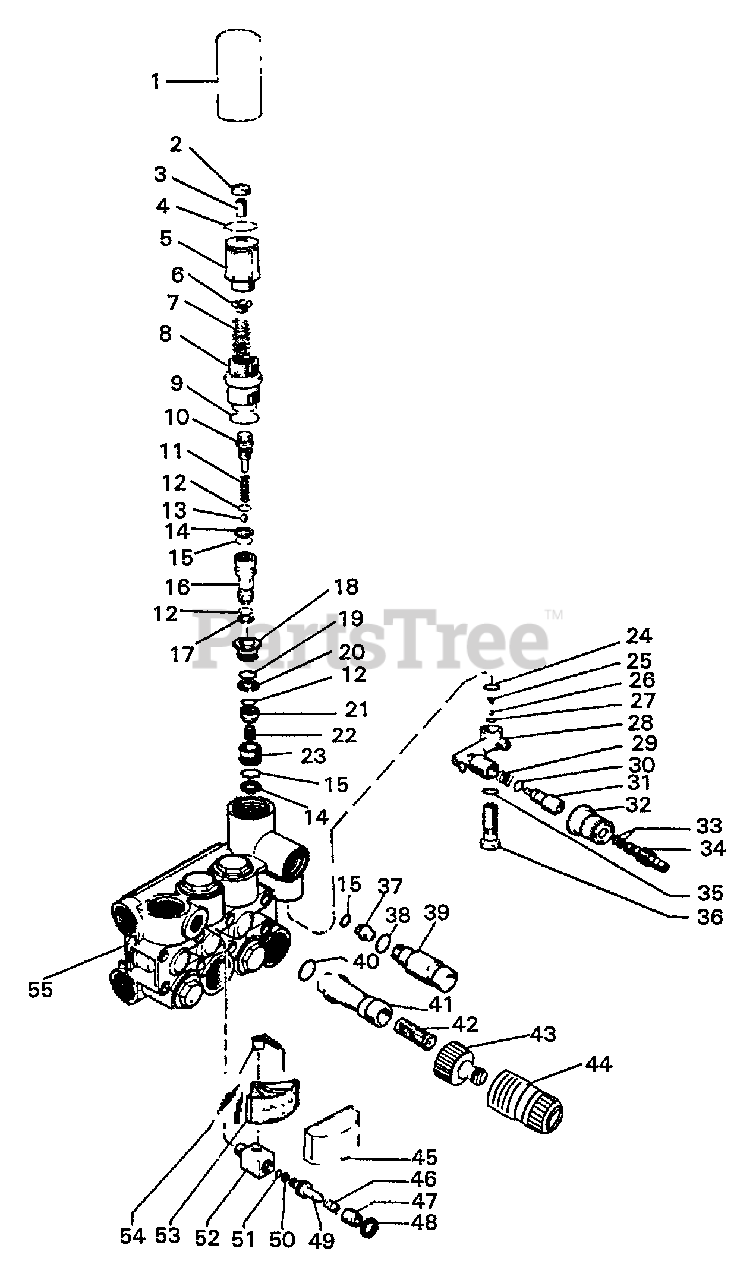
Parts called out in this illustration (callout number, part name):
1	KNOB, PRESSURE REGULATOR
2	NUT - 8
3	SCREW - 8X16
4	O-RING
5	SCREW, PRESSURE SET
6	PLATE, SPRING
7	SPRING
8	BUSHING, GUIDE
9	O-RING - .797 X.103
10	STOPPER, STROKE
11	SPRING
12	O-RING
13	BALL - 9/32"
14	RING, ANTI-EXTRUSION
15	O-RING
16	PISTON, CONTROL
17	RING, ANTI-EXTRUSION
18	GUIDE, VALVE
19	O-RING, .489 X.070
20	RING, ANTI-EXTRUSION
21	VALVE, BALL
22	SCREW - 5
23	SEAT, VALVE
24	O-RING
25	SPRING, TAPER
26	BALL
27	O-RING
28	BODY, INJECTOR
29	SPRING
30	O-RING
31	SHUTTER, INJECTOR
32	KNOB, CHEMICAL REGULATOR
33	O-RING
34	FITTING, HOSE BARB
35	O-RING
36	SEAT, CHEMICAL VALVE
37	NOZZLE, INJECTOR
38	O-RING
39	NIPPLE
41	NIPPLE
42	WASHER, STRAINER
43	COUPLING, QUICK CONNECT - MALE
44	COUPLING, QUICK CONNECT - FEMALE
45	COVER
46	SPRING
47	SCREW - 14X1
48	NUT - 14
49	PISTON
50	RING, BACK-UP
51	O-RING
52	BODY
53	DIAL
54	INDICATOR
55	MANIFOLD
